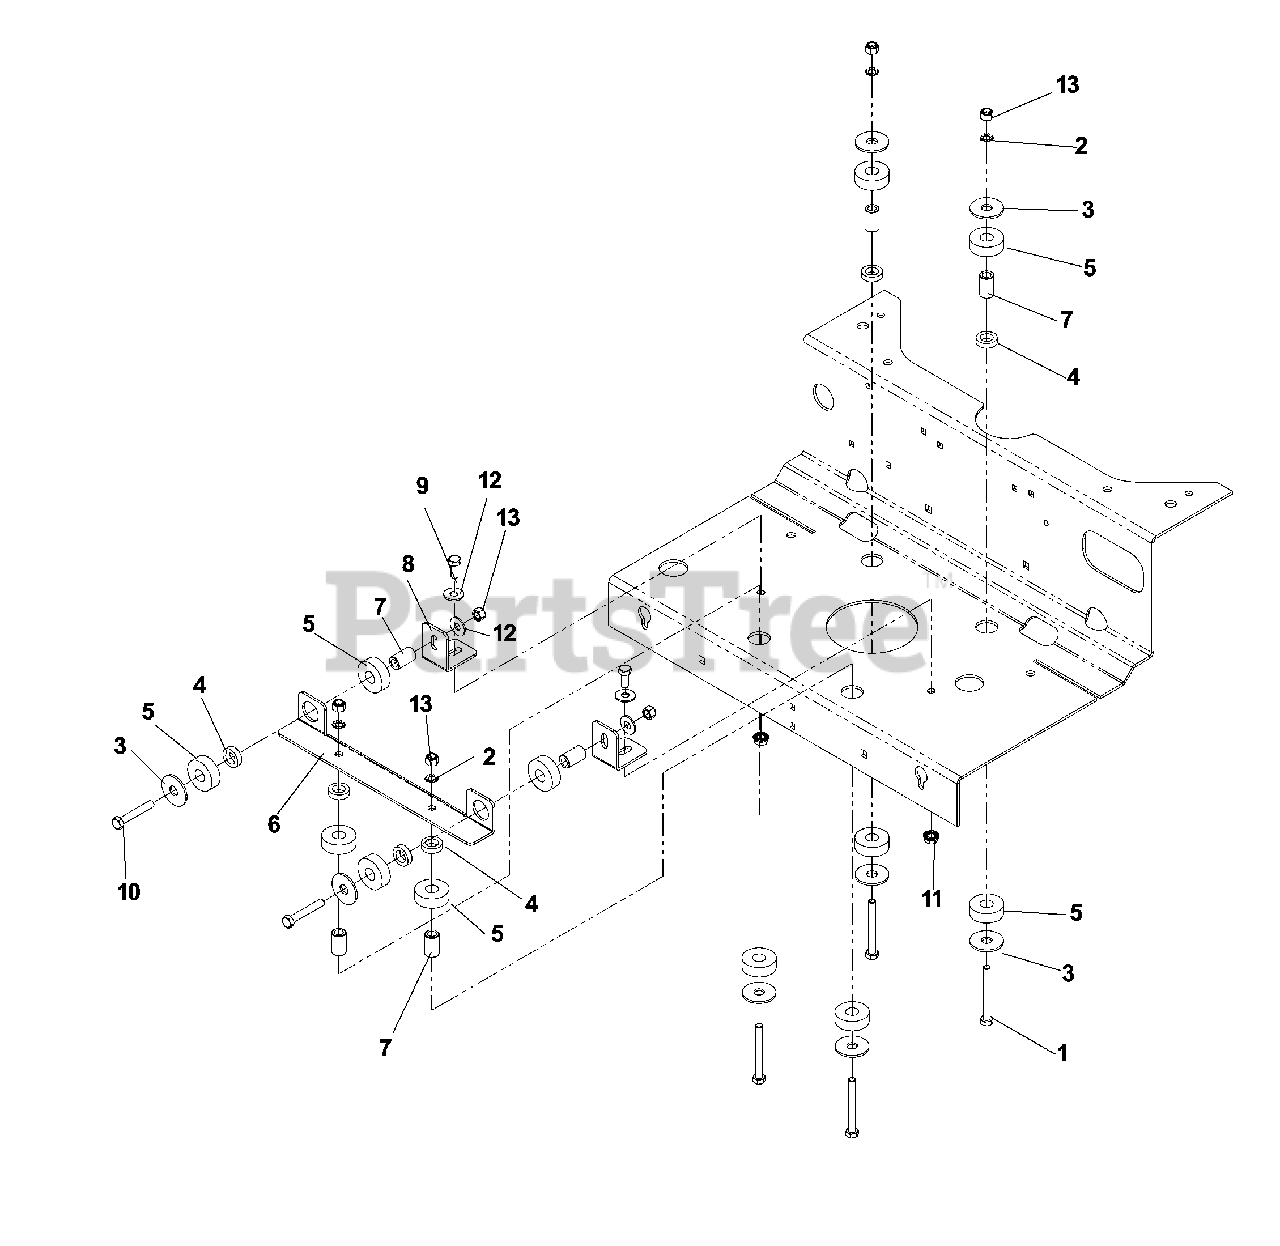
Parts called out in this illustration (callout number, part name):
1	HCS 5/16C X 2-3/4
2	WASHER 5/16 EXT STAR
3	7/16 HD FLAT WASHER
4	ISO-MOUNT INSERT
5	ISO-MOUNT BUSHING
6	ISO MT. PLATE
7	ISO MT. BUSHING
8	ISO MT. BRKT.
9	HCS 5/16C X 3/4
10	HCS 5/16-18X2
11	NUT 5/16C WHIZ
12	WASHER 5/16 FLAT
13	NUT 5/16 NYLOC
